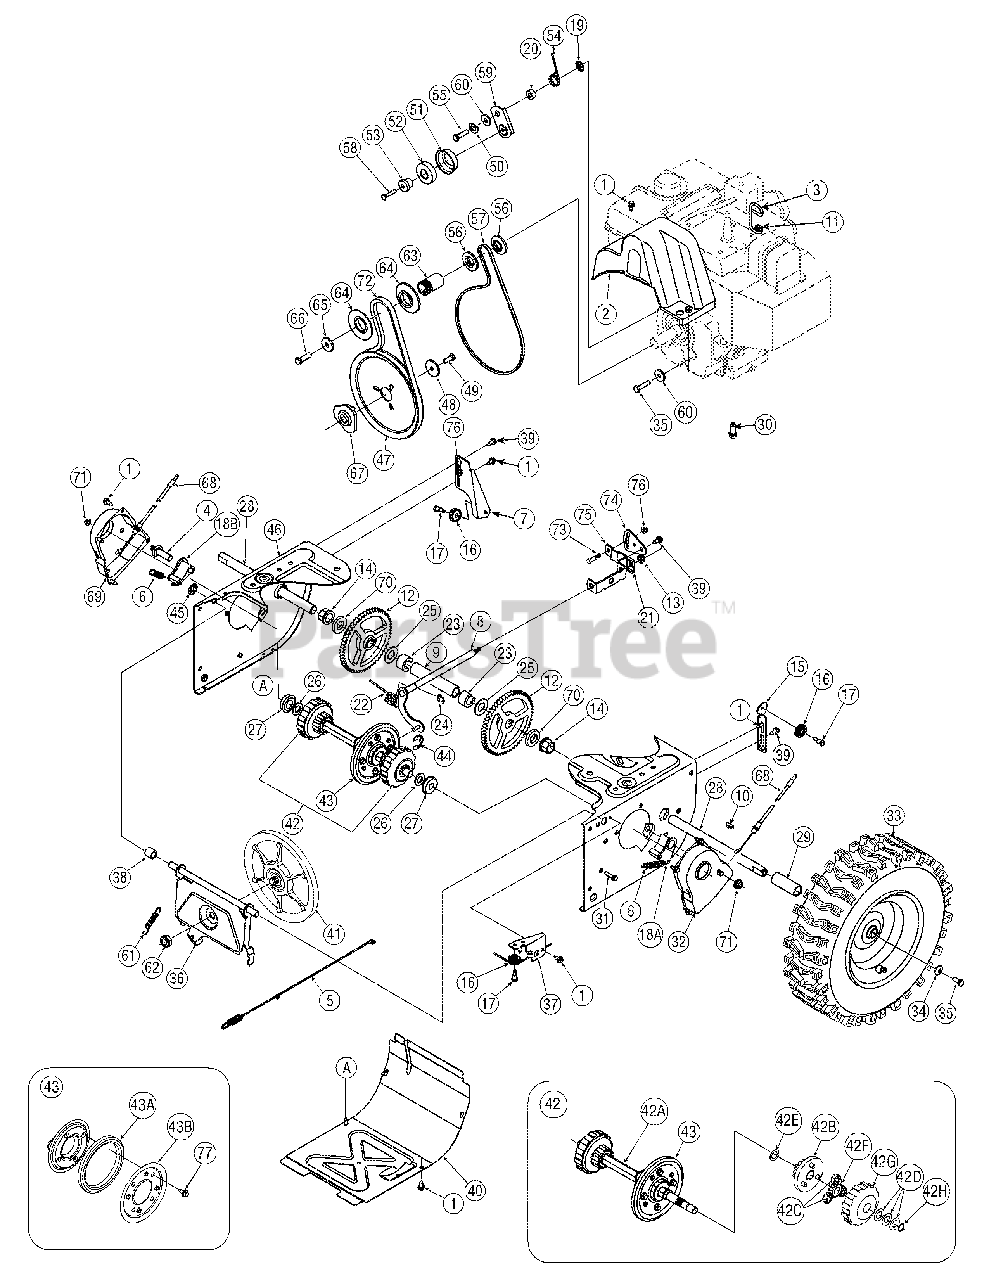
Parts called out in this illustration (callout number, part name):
1	Hex Wash Hd TT Scr. 1/4-20 x .625
2	Belt Cover (w/4 Way Chute Control)
2	Belt Cover (Std.)
3	Cable Control Wire
4	Drive Shaft Actuator
5	Drive Clutch Cable 44.83" Lg.
6	Extension Spring .5 OD x 1.71 Lg.
8	Shift Rod Ass’y
9	Axle Support Tube
10	#9 HI-Pro Key 3/16 x 3/4 Dia HT
11	Hex Wash Hd Tapp Scr 5/16-18 x 1.00
12	Gear, 56T
13	Flange Lock-Nut 5/16-18 Gr. F Nylon
14	Hex. Flange Bearing.751" ID
16	Cable Guide Roller
17	Hex Shld.Scr.1/4-28 x .375
18A	Dogg Assembly - LH
18B	Dogg Assembly - RH
19	Push Nut
20	Spacer .340 x .750 x .360" Lg.
21	Shift Spacer Bracket
22	Torsion Spring .750 ID x .968" Lg.
23	Spacer
24	Retaining Ring
25	Flat Washer .760 ID x 1.49 OD
26	Flat Washer .580 x 1.125 x .080
27	Ball Bearing
28	Axle
29	Spacer
30	Hex Wash HD Tap Scr 3/8-16 x .88
31	Hex Bolt 1/4-20 x 1.00
33	Axle 16 x 4.8 size
34	Cupped Washer .345 ID x .88 OD x .060
35	Hex L-Bolt 5/16-24 x .75 Gr. 5
38	Spacer .513 ID x 1.0
39	Shoulder Screw .373 x .105:TT 1/4-20
42	Drive Shaft Assembly (w/o Friction Wheel Ass'y)
42A	Hex Drive Shaft (500)
42B	Planetary Carrier Ass'y
42C	Gear 12T
42D	Flat Washer .58 x 1.12 x .02
42E	Flat Washer 5/8 ID x 1.0 OD
42F	Gear 18T
42G	Ring Planetary Gear Ass'y (500)
42H	Retaining Ring 1.56 diam.
43	Friction Wheel Assembly
43A	Friction Wheel Rubber
43B	Friction Plate
44	Retainer Ring
45	Cap Speed Nut 1/4 Rod
47	Auger Pulley
48	Flat Washer .34 x 1.50 x .150
49	Hex Bolt 5/16-24 x 0.875
50	L-Wash 5/16 ID
51	Bearing Sleeve
52	Ball Bearing 20 x 47 x 14:6204:DS
53	Spacer
54	Torsion Spring .850 ID x .354" Lg.
55	Hex HD. Cap Scr. 5/16-24 x 1.25 Lg.
56	Pulley HalfL 1/4 V x 1.5 OD
57	Belt 33.0" Lg.
58	Hex Bolt 1/4-20 x 1.25
59	Wheel Drive Idler Bracket
60	Shoulder Spacer
61	Extension Spring 3/8 OD x 2.50
62	Jam L-Nut 5/8-18 Gr. 5 Nylon
63	Spacer .875 ID x 1.185 OD
64	Pulley Half
65	Flat Washer .40 ID x 1.25 OD x .160
66	Hex Screw 3/8-24 x 1.25
67	PulleyAdapter
68	Steering Cable
70	Axle Spacer
71	Flange Lock-Nut 3/8-16 Gr. F Nylon
72	Belt .5 x 35.0" Lg.
73	Hex Bolt 1/4-20 x .62 Gr. 5
76	Flange Lock-Nut 1/4-20 Gr. F Nylon
77	Hex Wash. Hd. TT Scr. 1/4-14 x .625
